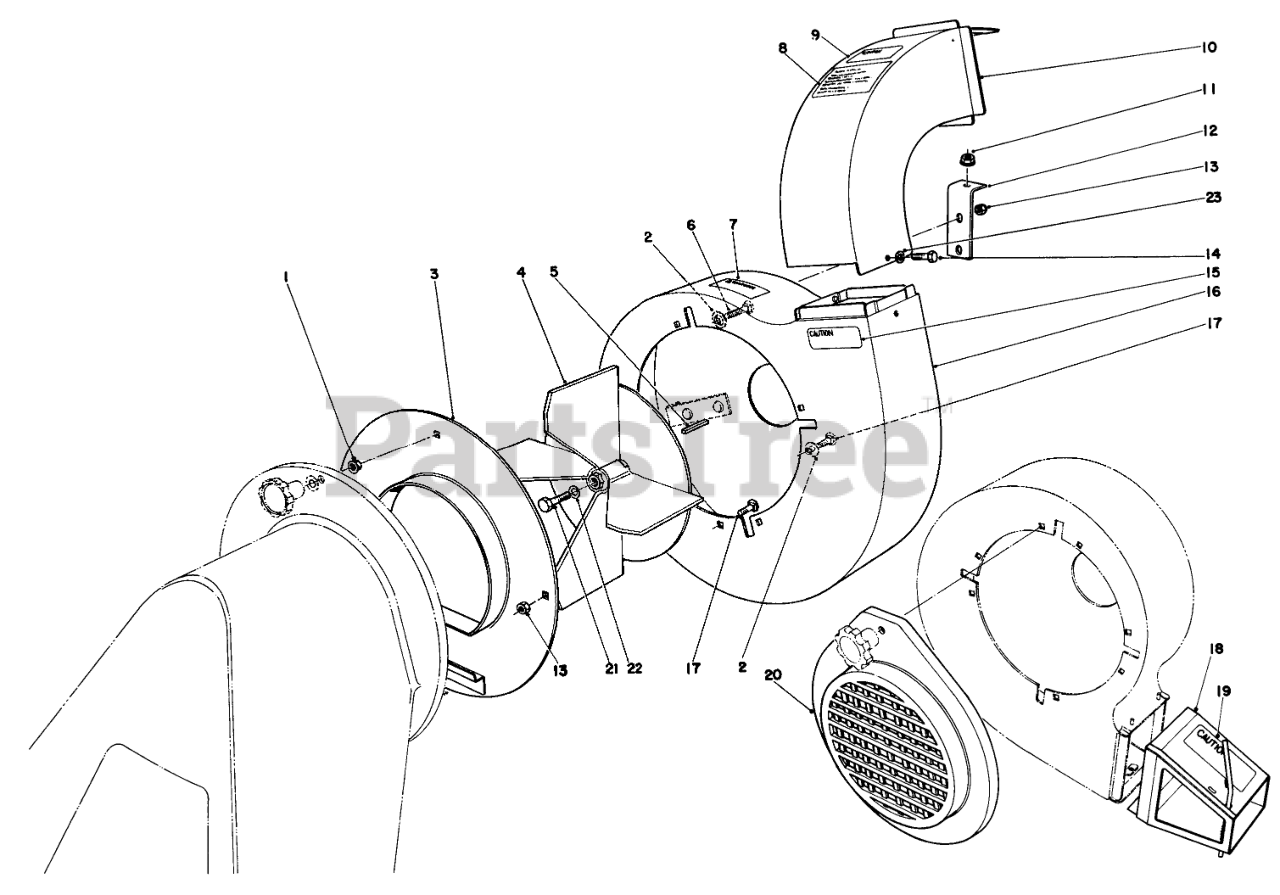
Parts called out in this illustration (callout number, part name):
1	NUT-FLANGE
2	WASHER-FLAT
3	Blower Cover
4	Fan
6	BOLT-CARR
7	ROTATE WARNING DECAL
8	TORO ADVER DECAL
9	DECAL CAUTION BAG
10	Chute-Vacuum
11	NUT-LOCK, NI
12	Bracket-Housing
13	NUT-LOCK, NI
14	SCREW-HH
15	WARNING DECAL
16	Blower Housing
17	SCREW-CARR
18	Blower-Exhaust(Incl Ref. #19)
19	EXHAUST DECAL
20	INTAKE-BLOWER
21	WASHER-BELLEVILLE
22	SPEC SCREW
23	WASHER-BELLEVILLE
